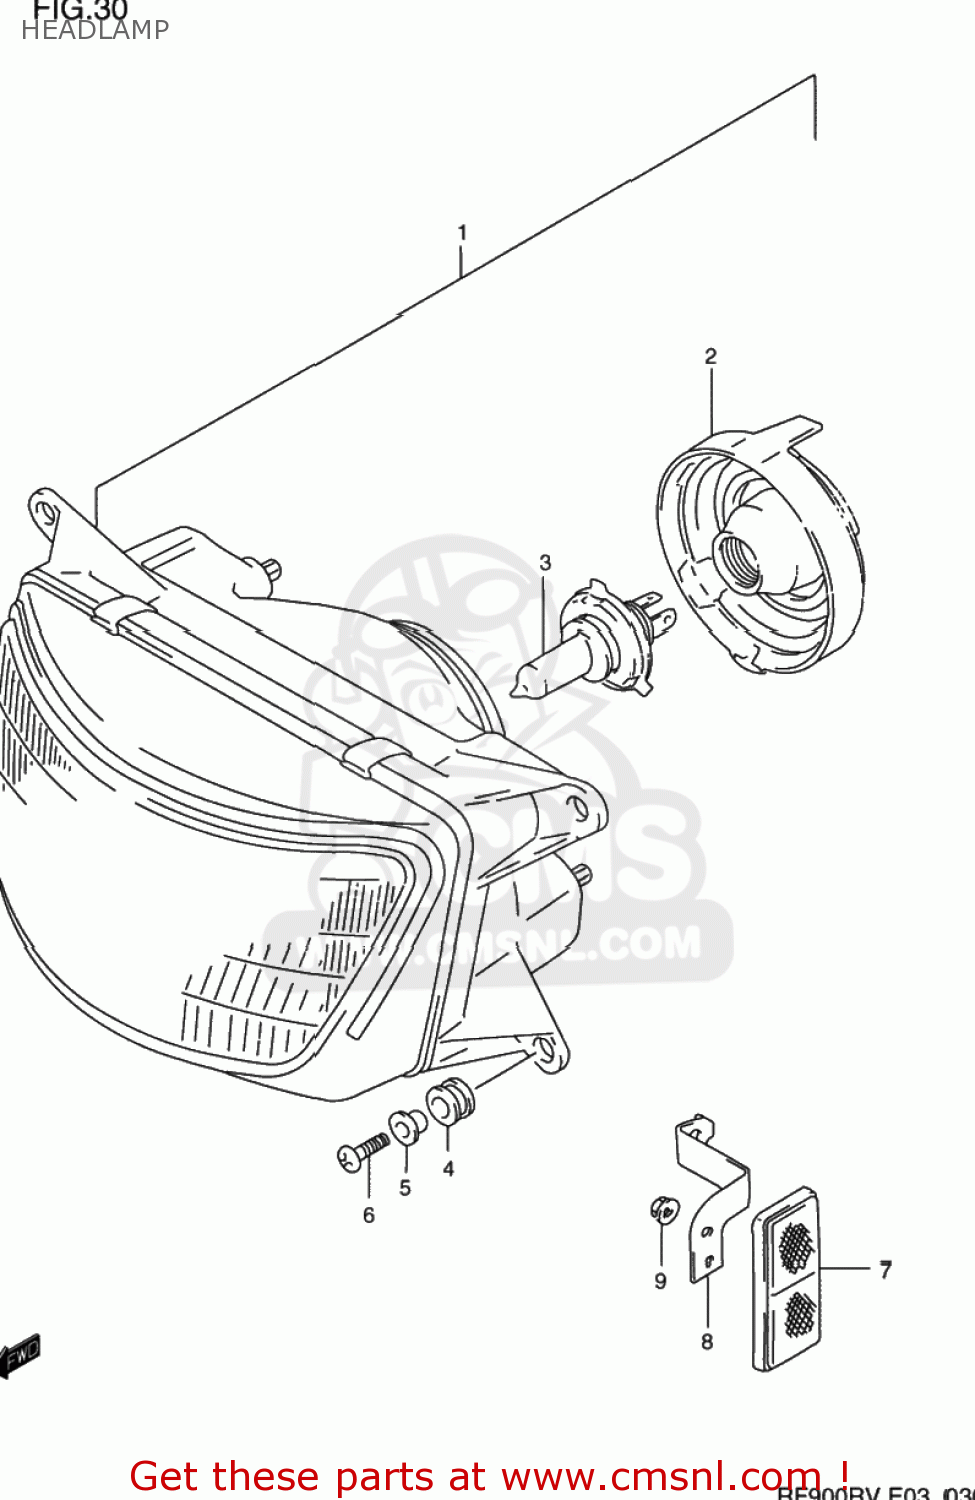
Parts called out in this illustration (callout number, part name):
1	HEADLAMP ASSY
2	COVER,SOCKET
3	BULB(12V60/55W,H4)
4	CUSHION
5	WASHER
6	SCREW
7	REFLECTOR,REFLEX FR
8	BRACKET,FR SIDE REFLECTOR,R
9	NUT
